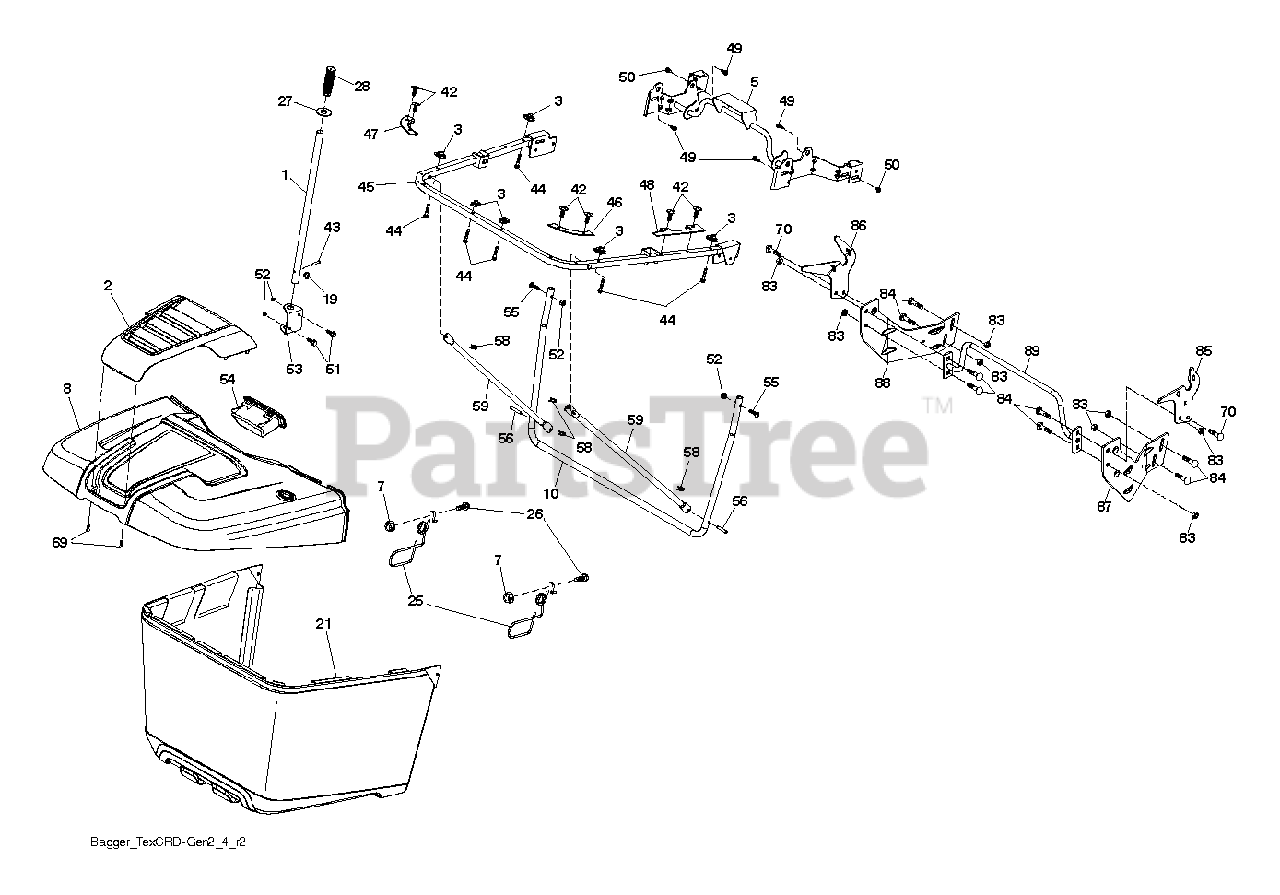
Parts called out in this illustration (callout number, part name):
1	TUBE.HANDLE.BAGGER.CRD/SRD.BLA
2	APPLIQUE.BAGGER
3	1/4-20 U NUT
5	FRAME TEX_CRD_GEN2 UPPER PIVOT
7	NUT T
8	BAGGER TOP
10	FRAME TEX_CRD_GEN2 BAGGER FRAM
19	PIN.COTTER.5/16.BOW TI
21	BAG FRAME BAGGER ASSEMBLY. HUS
25	LATCH LATCH. BAG. CRD GEN 2
26	SCREW HEX CRT
27	GROMMET RUBBER GROMMET, DUMP T
28	GRIP.HANDLE.BLACK
42	CLIP CHRISTMAS TREE CLIP
43	RIVET,DRILLED
45	FRAME TEX_CRD_GEN2 UPPER U FRA
46	CONNECTOR RIGHT BAGGER CORNER
47	CONNECTOR LEFT BAGGER CORNER C
48	BAFFLE BAGGER SIDE CLOSE-OUT
49	BOLT, SHOULDER 5/16-18
50	BOLT, 5/16-18 X 1 3/4
51	BOLT.CARR.SQNK.5/16-18UNC.X3/4
52	NUT.71038.31-18.HEX.NYLOCK
53	BRACKET DUMP HANDLE BRACKET, T
54	HANDLE BAGGER TOP FRONT HANDLE
55	BOLT
56	PIN.CLEVIS.183
58	RETAINER CLIP PM
59	TUBE BAGGER SPREADER TUBE, TEX
69	SCREW,#8.FLAT.HEAD.DRILL.TIP
70	SCREW, 3/8-16X3/4
83	NUT
84	BOLT D
85	BRACKET.RH.PIVOT.MAN.DUMP.BLAC
86	TUBE.WELD.OFSET.STRUT.BAG.X431
87	BRACKET.RH.MID.SUP.BAG.TEX.CRD
88	BRACKET.LH.MID.SUP.BAG.TEX.CRD
89	TUBE.WELD.OFSET.STRUT.BAG.X431
